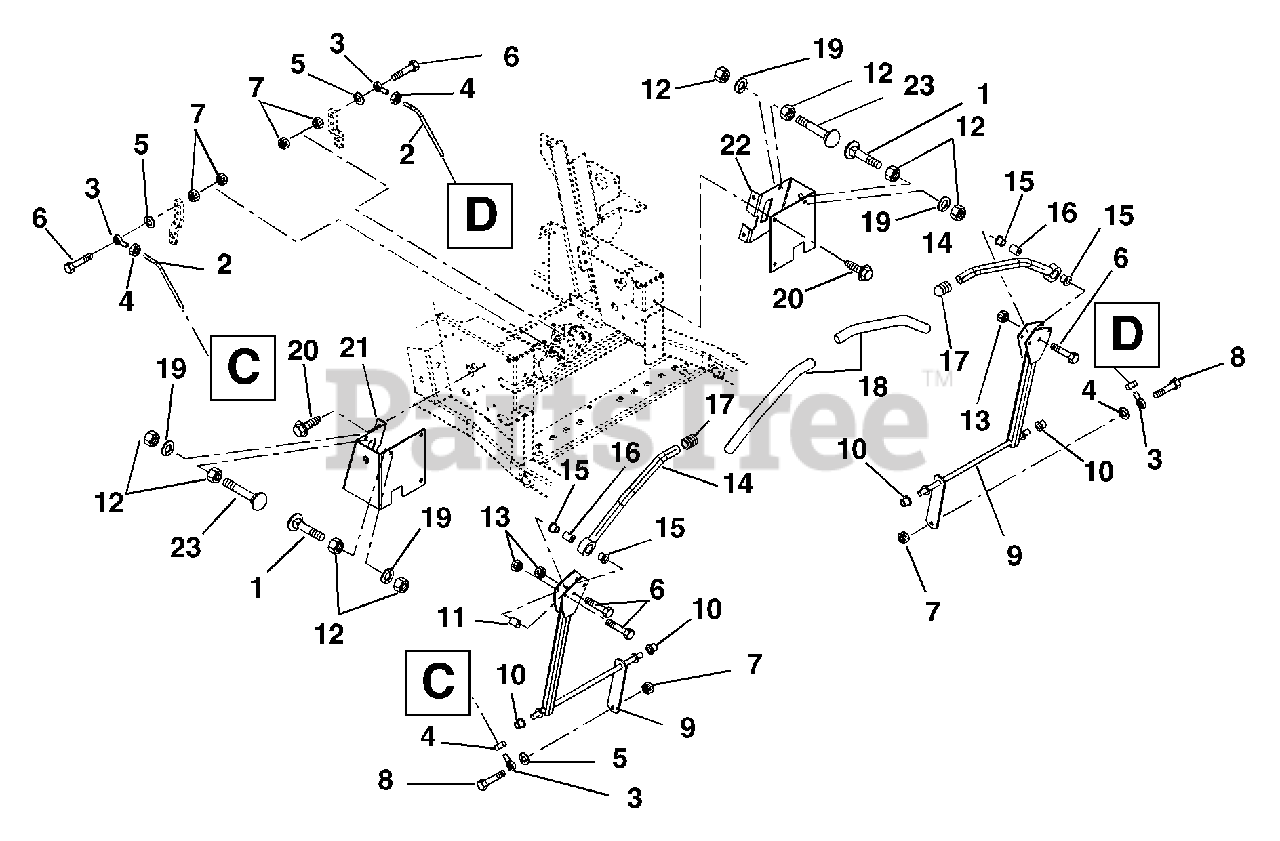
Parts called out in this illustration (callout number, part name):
1	Bolt-Round Head Square Neck .38-16 x 1.50
2	Rod-Steering Adjustment
3	Rod End .312 Right-Hand-Female
4	Nut-Jam .31-24
5	Washer-Locking .31 x .078
6	Bolt-Hex .31-18 x 1.75 Grade 5
7	Nut-Locking-Center .31-18
8	Bolt-Hex .31-18 x 1.50 Grade 5
9	Rod-Steering
10	Bushing-Flange .515 x .750 x .745 x 1.00
11	Eccentric
12	Nut-Hex .38-16
13	Nut-Locking-Center .31-18
14	Handle Weldment Left-Hand
14	Handle Weldment Right-Hand
15	Bushing-Flange-Nylon .762 x 1.48 x .44
17	Caplug- Handlebar
18	Grip-Handlebar
19	Washer-Locking .38 x .094
20	Screw-Tapping .38-16 x .75 Hex Washer Head
21	Mount-Steering Rod-Right Hand
22	Mount-Steering Rod-Left Hand
23	Bolt-Round Head Square Neck .38-16 x 2.00
